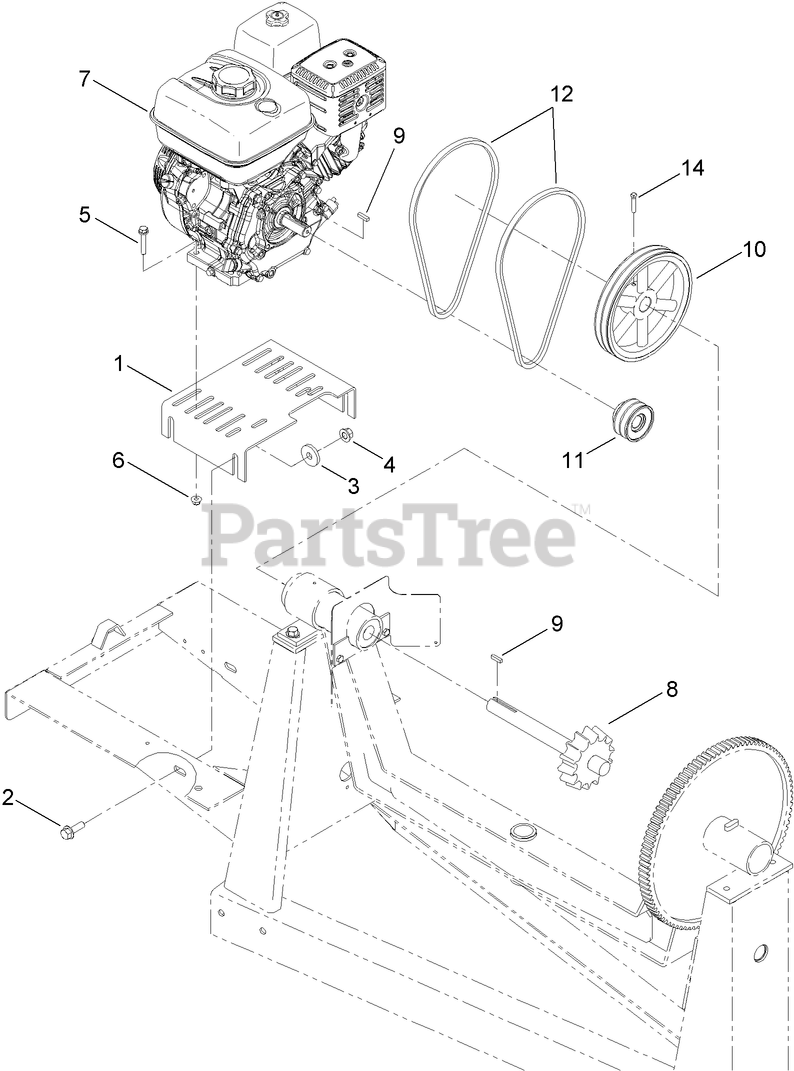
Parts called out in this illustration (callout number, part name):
1	BASE-MOTOR
2	SCREW-HHF
3	WASHER-FLAT
4	NUT-LOCK
5	SCREW-HHF
6	NUT-HF, NI
7	ENGINE-HONDA, GX240
8	SHAFT-DRIVE
11	SHEAVE
12	BELT-V
14	SCREW-SET
